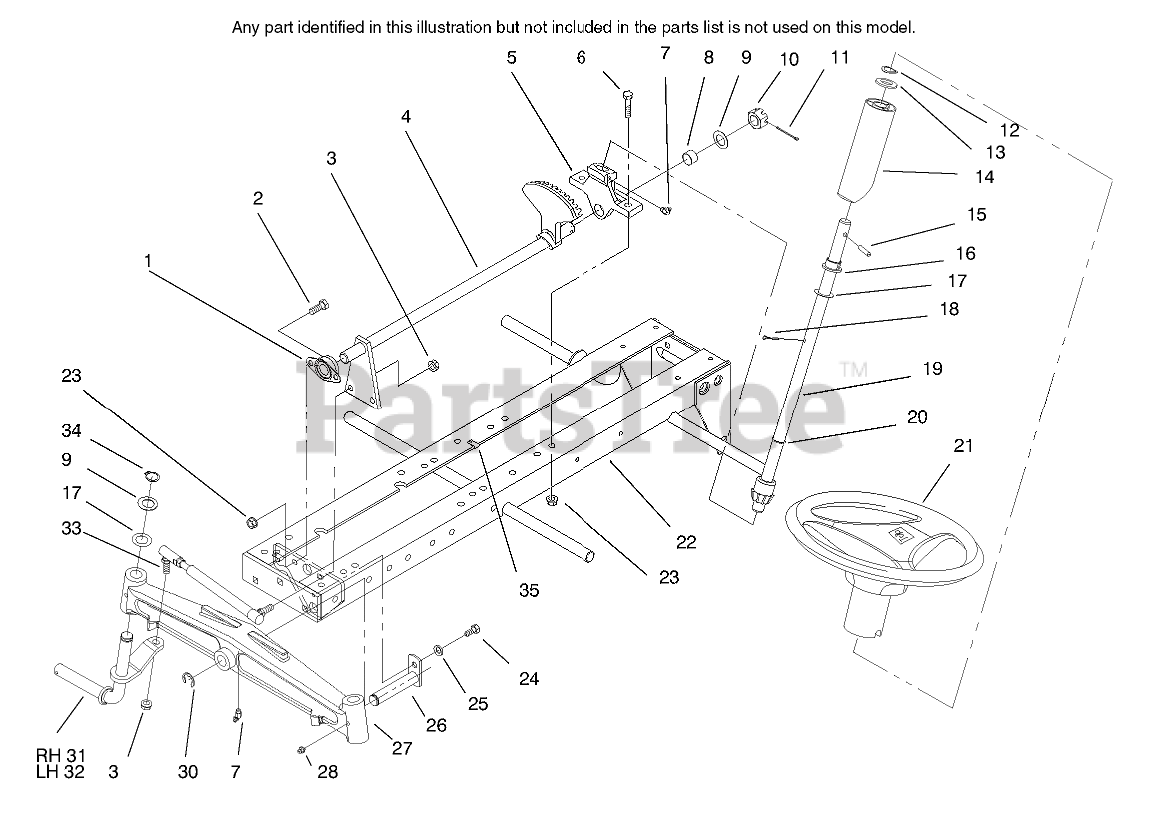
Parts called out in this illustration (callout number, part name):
1	BEARING-FLANGED
2	SCREW-HH
3	NUT-LOCK
4	Shaft-Steering
5	Support-Lower Steering
6	SCREW-HH
7	FITTING-LUBE, 45 DEG
8	BEARING-BRONZE
9	WASHER
10	NUT-HEX, SLOTTED
11	PIN-COTTER
12	WASHER-BOWED
13	WASHER-FLAT
14	TUBE-STEERING
15	PIN-ROLL
16	BEARING-FLANGED
17	WASHER-SHIM
18	PIN-COTTER
19	STEERING SHAFT ASM
20	O-RING
21	WHEEL - STEERING 15"
21:1	COVER-WHEEL
22	FRAME ASM
23	NUT-LOCK, NI
24	SCREW-HH
25	WASHER-LOCK
26	PIN AND PLATE ASM
27	AXLE-FRONT
28	FITTING-GREASE
30	E-RING
31	SPINDLE ASM-RH
32	SPINDLE ASM-LH
33	ASM-Rod
34	RING-RETAINING
35	CLIP-WIRE
